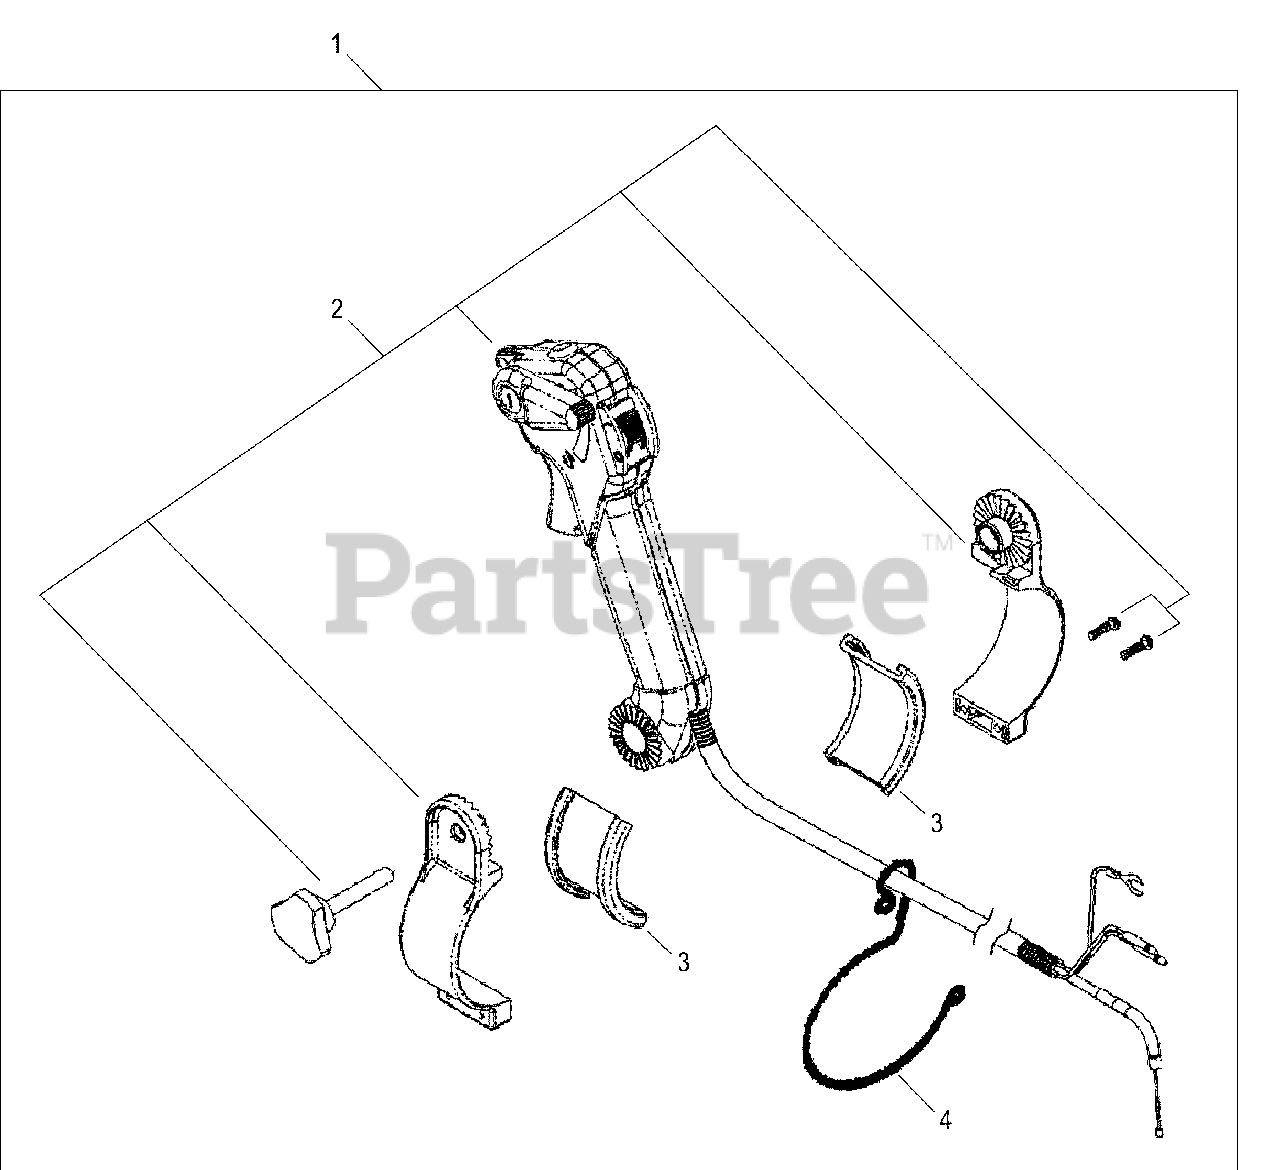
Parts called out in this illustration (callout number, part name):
1	THROTTLE LEVER ASSY
2	THROTTLE LEVER ASSY
3	SPACER
4	CLAMP
